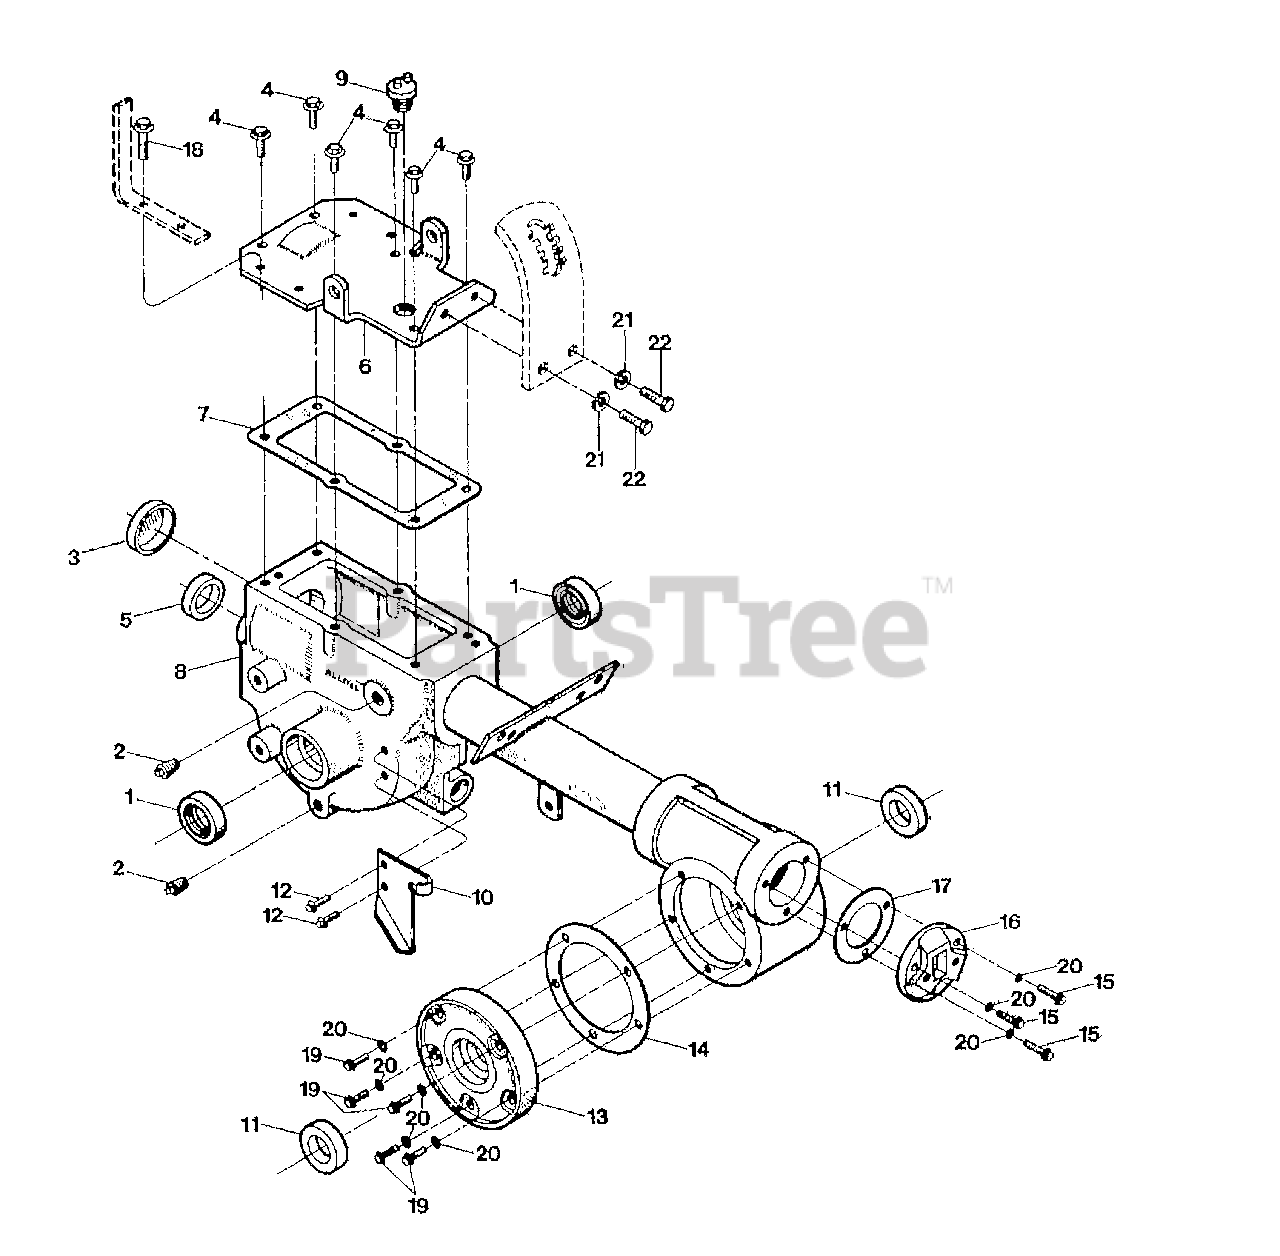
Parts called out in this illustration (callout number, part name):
1	SEAL-OIL WHEELSHAFT
2	PLUG-PIPE 1/4 NPT
3	SEAL-BORE
4	SCR-HFLK 5/16-18X.75 ZP
5	SEAL-PINION SHAFT PT/85030/00
6	KIT-COVER TRANS W/HDW
7	GASKET-TRANS COVER
8	ASSM-TRANS A-UNIT P/ECHO
9	PLUG-OIL FILL 3/4-10
10	PLATE-CABLE MT PNT
11	SEAL-TILLER SHAFT
12	SCR-HFLK 5/16-18X.62 G5ZP
13	COVER-TILLER HSG MACH
14	GASKET-TILLER COVER
16	CAP-REAR #1115
17	GASKET-BRG COVER
18	SCR-HFLK 5/16-18X1.00 ZP
20	WASHER - NYLON
21	WASHER-LK .375 @ DEPL
22	SCR-HH 3/8-16X.75 G5 ZP
